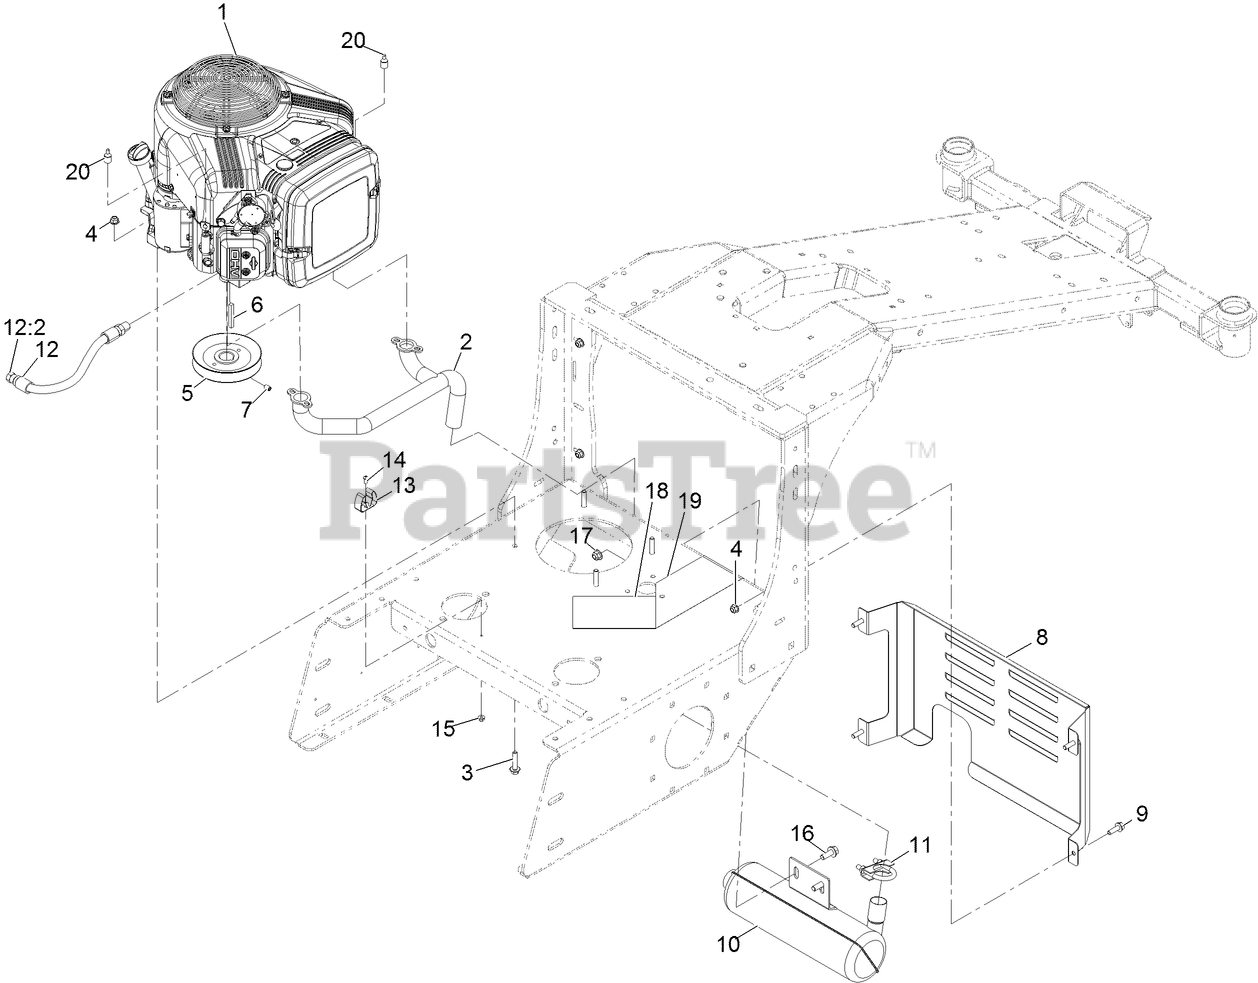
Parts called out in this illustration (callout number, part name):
1	Engine - Vanguard
2	18 HP EXHAUST MANIFOLD 4
3	SCREW-HHF
4	NUT-HF, NI
5	PULLEY-DRIVE
7	Setscrew-HSH
8	GUARD-ENGINE, AE
9	SCREW-HH
10	23HP BRIGGS MUFFLER(18HP
11	Clamp-Muffler
12	HOSE-DRAIN,3/8X15.75W/JIC
13	Holder-Tool, Clip
14	Screw-HSBH
15	Nut-Hex Flange
16	SCREW-HHF 3/8-16 X 1
17	NUT-HF, NI
18	ADHESIVE BACK, HEAT BARRI
19	TAPE-HEAT
20	Tube-Heat Shrink, 1/2
